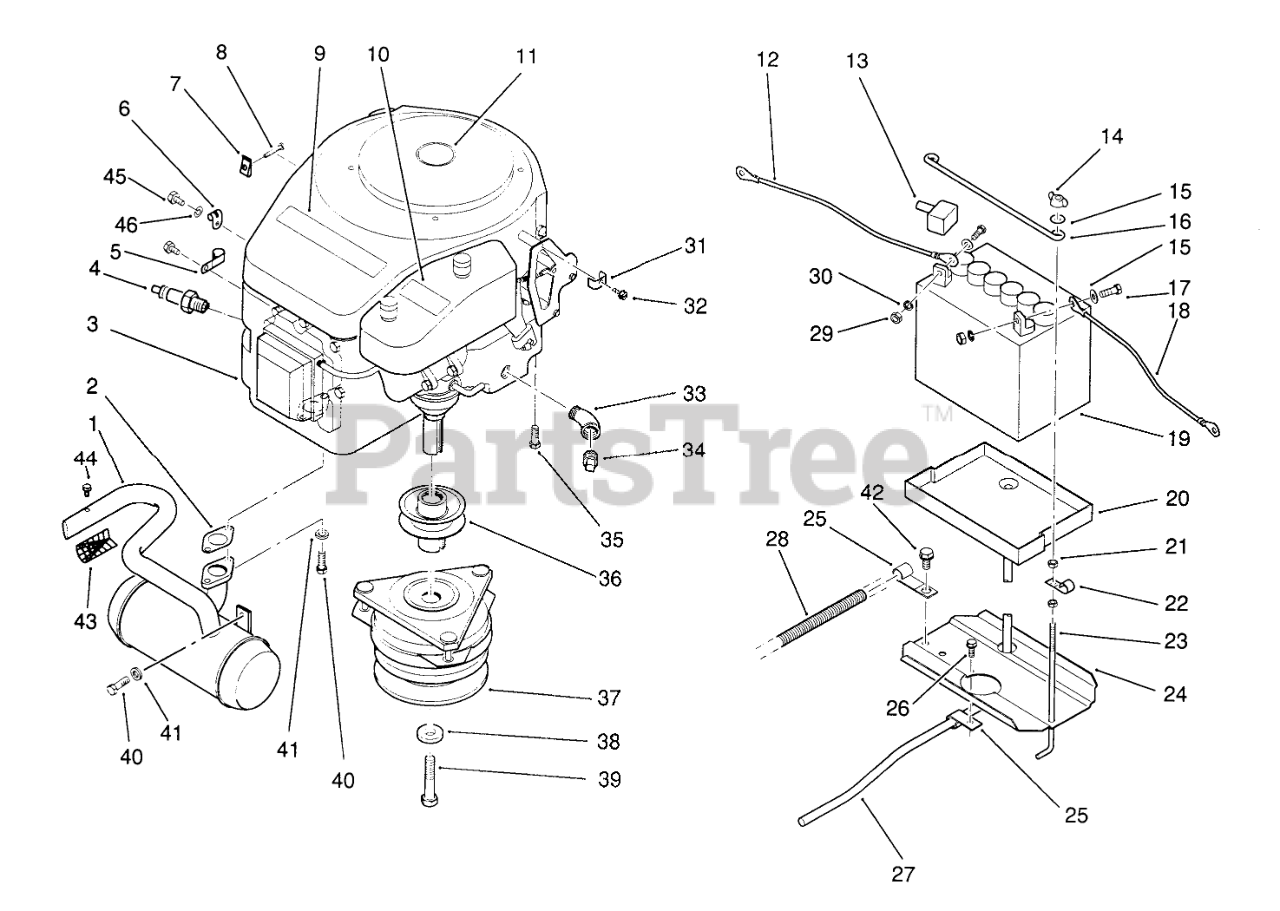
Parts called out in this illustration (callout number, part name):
1	MUFFLER
2	GASKET-EXHAUST
3	ENGINE-E14OV/11207
4	Plug-Spark
5	J-CLIP
6	CLEVIS
7	J-CLIP
8	HHCS M8X1.25X15
9	DECAL-PWR PLUS
10	DECAL-14.0 POWER PLV
11	DECAL-TORO ENGINE
12	WIRE - 14" BLACK
13	Boot
14	Nut
16	ROD-BATTERY HOLD DWN
17	Bolt
18	ASS'Y-WIRE
19	Battery
20	TRAY-BATTERY
21	Nut
22	CLAMP
24	Tray
25	CLIP
26	SCREW
27	TUBE-21" BATTERY DRAIN
28	WIRE-HARNESS
29	Nut
30	Washer
31	Clamp
32	Screw
33	STREET ELBOW 45DEGRE
34	Plug
35	Bolt
36	PULLEY-ENGINE HYD R
37	Clutch
38	WASHER
39	HHCS-M10X1.5X110 ESL
40	HHCS M8X1.25X20
41	Lockwasher
42	Screw
43	Arrester-Spark
44	BOLT-HEX S.T. #8X1/2
45	Screw
46	Washer
